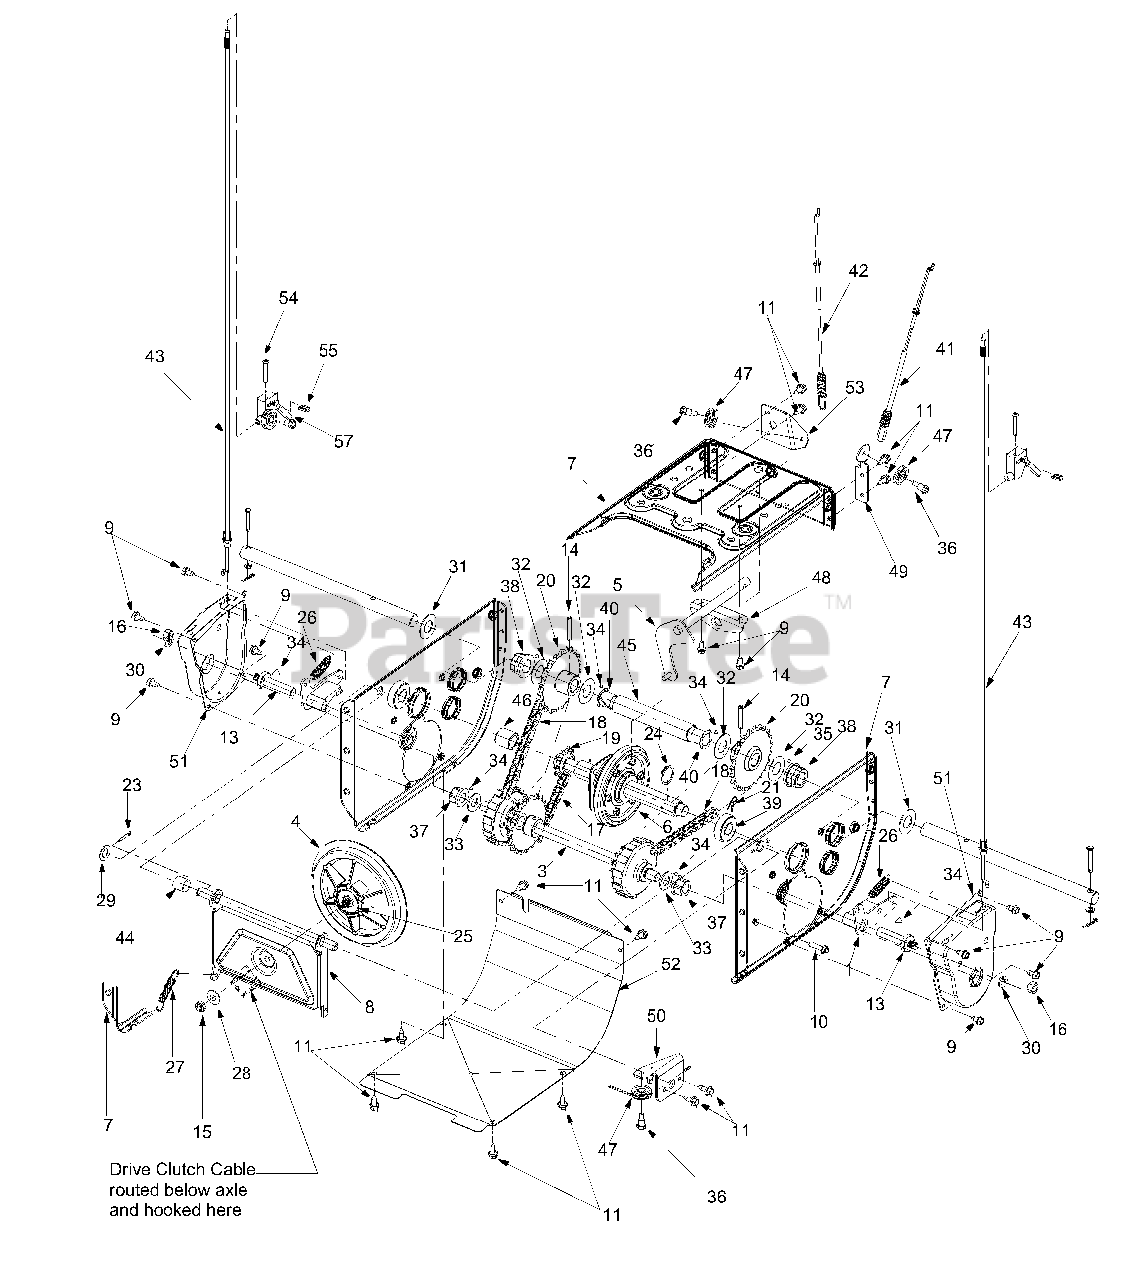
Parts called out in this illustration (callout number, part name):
1	Dogg Assembly: RH
2	Dogg Assembly: LH
3	Shift Assembly: Steerable Drive
4	Friction Wheel Disc Assy.
6	Friction Wheel Assembly, Complete
10	Hex Washer Hd. TT Screw 1/4-20 x 1.0"
11	Hex Washer Hd. TT Screw 1/4-20 x .625"
12	Drive Shaft
13	Actuator Shaft
15	Jam Nut 3/8-24 Gr.8
16	Hex Nut: 3/8-16
17	Chain
18	Chain
19	Sprocket: 10T
20	Sprocket
21	Cotter Pin
22	Flat Washer
23	Cotter Pin
24	Snap Ring
25	Adhesive: Loctite
26	Extension Spring
27	Extension Spring
28	Bell Washer
29	Flat Washer
30	Lock Washer
32	Flat Washer
33	Flat Washer
34	Lubricant: 6 in 1
35	Grease
36	Shoulder Screw
37	Hex Flange Bearing
38	Hex Flange Bearing
39	Ball Bearing
40	Flange Bushing
41	Auger Clutch Cable
42	Drive Clutch Cable
43	Steering Cable
44	Spacer
45	Support Tube: Axle
46	Spacer
47	Roller Cable
55	Weld Nut
56	Cable Tie
57	Turn Trigger
